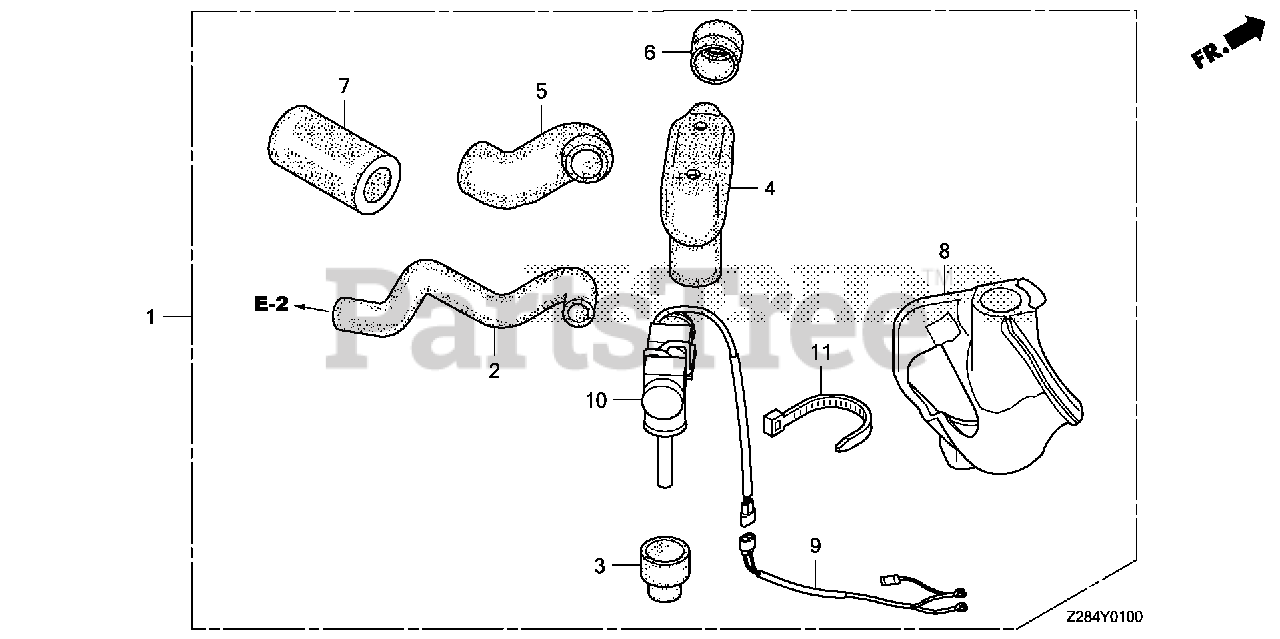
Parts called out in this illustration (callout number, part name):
1	HEATER KIT, BREATHER
2	TUBE A, BREATHER
3	TUBE B, BREATHER
4	INSULATOR, BREATHER HEATER
5	INSULATOR, BREATHER TUBE
6	TUBE C, BREATHER
7	INSULATOR B, BREATHER TUBE
8	INSULATOR, AIR IN. JOINT
9	SUB-WIRE ASSY.
10	HEATER ASSY., BREATHER (L)
11	BAND, HARNESS (BLACK)
